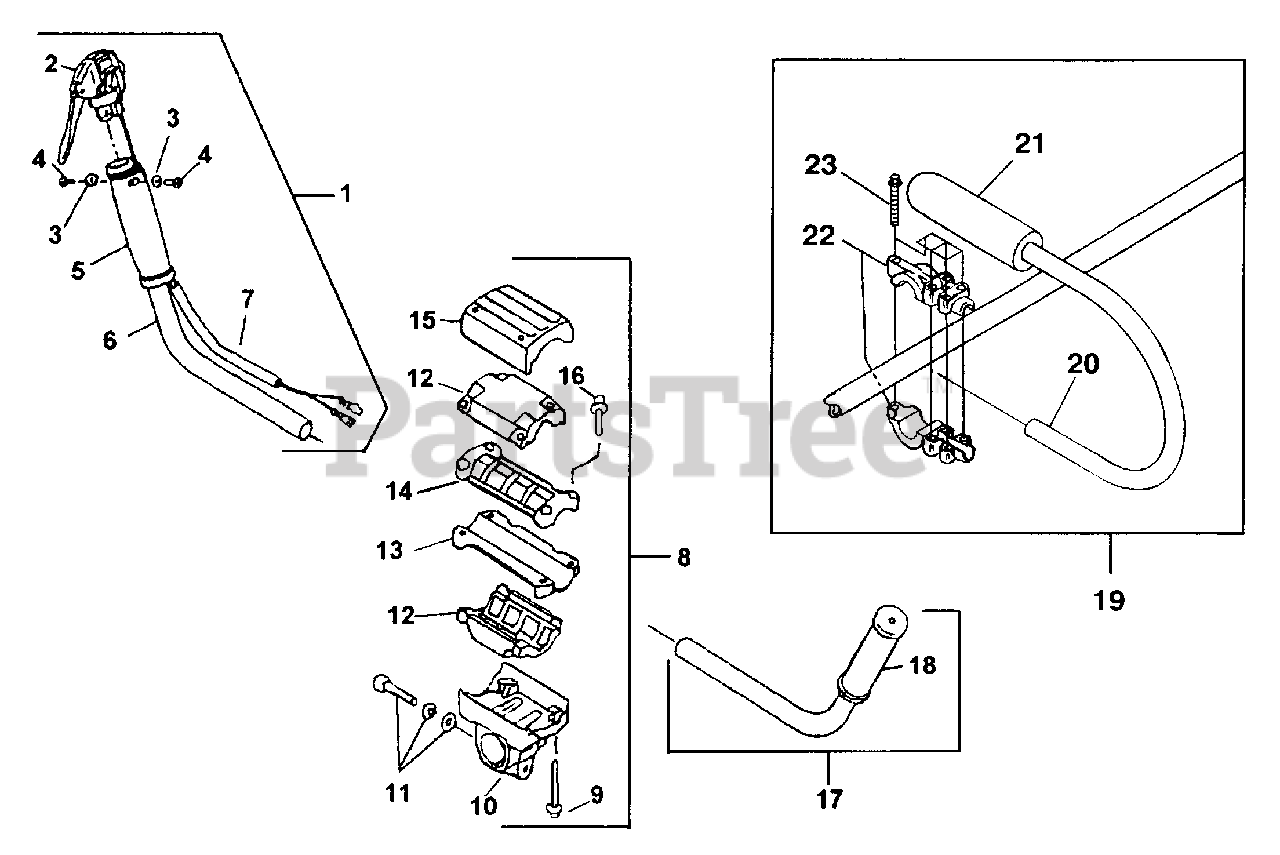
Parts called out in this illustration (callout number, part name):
1	Handle Assembly R.H.
2	Throttle Switch Assembly
3	Washer
4	Screw
5	Grip R.H.
6	Handle
7	Tube W/Wire Harness
8	Handle Joint Assembly
9	Bolt
10	Handle Joint, Bottom
11	Screw & Washer
12	Isolating Rubber
13	Pipe Fitting
14	Pipe Fitting
15	Handle Joint, Top
16	Bolt
17	Handle Assembly L.H.
18	Grip L.H.
19	Handle Assembly
20	Handle
21	Grip
22	Bracket Assembly
23	Bolt
